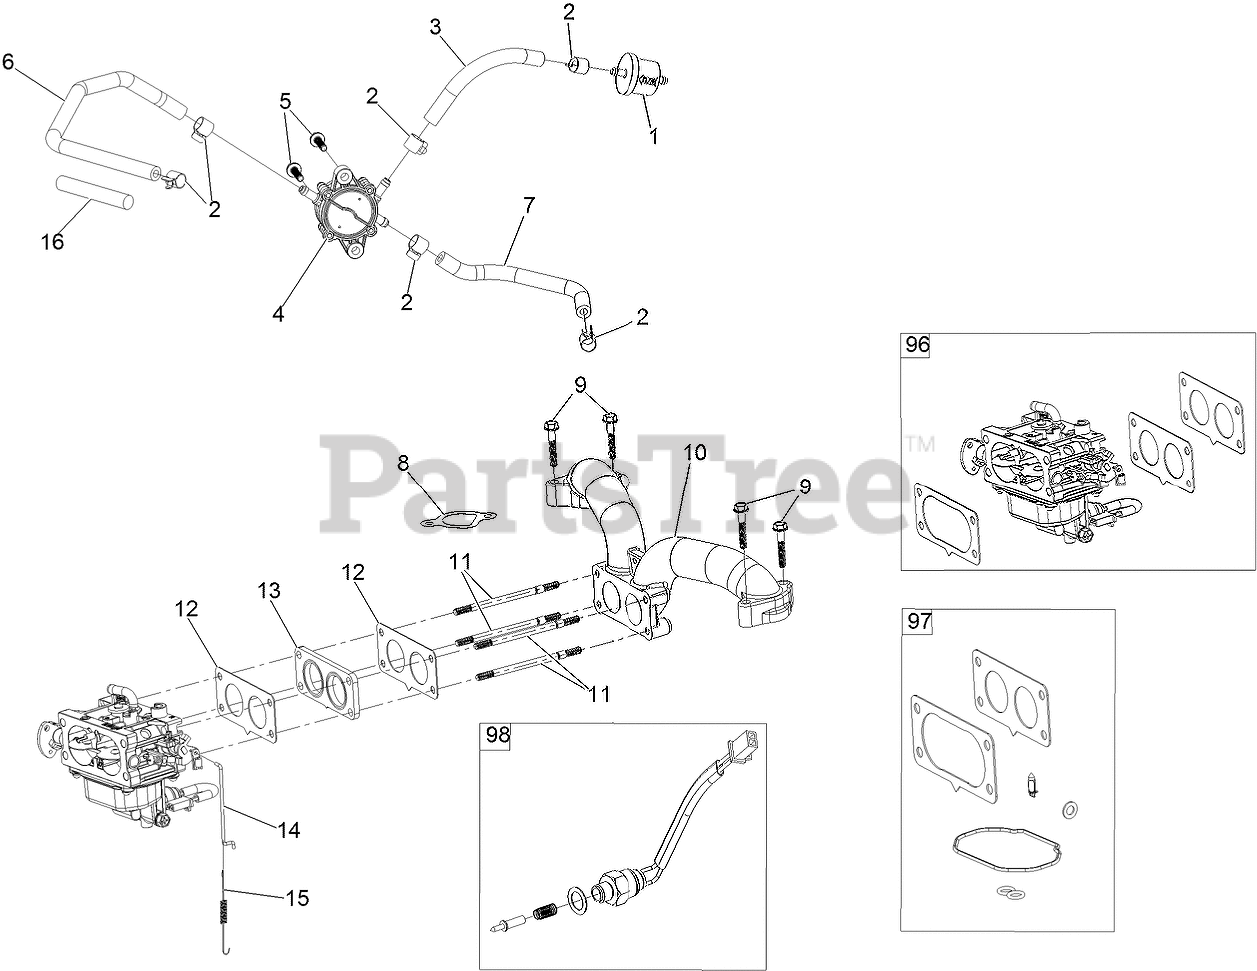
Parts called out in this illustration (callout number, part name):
1	FILTER-FUEL
2	CLAMP-FUEL LINE
3	LINE-FUEL
4	PUMP-FUEL
5	SCREW-HHF
6	HOSE-FUEL
7	HOSE-FUEL
8	GASKET-INTAKE
9	SCREW-HHF
10	MANIFOLD-INTAKE
12	GASKET-CARBURETOR
13	INSULATOR-CARBURETOR
14	LINKAGE-THROTTLE
15	SPRING-RETURN, THROTTLE
16	SLEEVE-FUEL LINE PROTECTO
96	CARBURETOR REPLACEMENT KI
97	CARBURETOR REPAIR KIT
98	SOLENOID KIT
